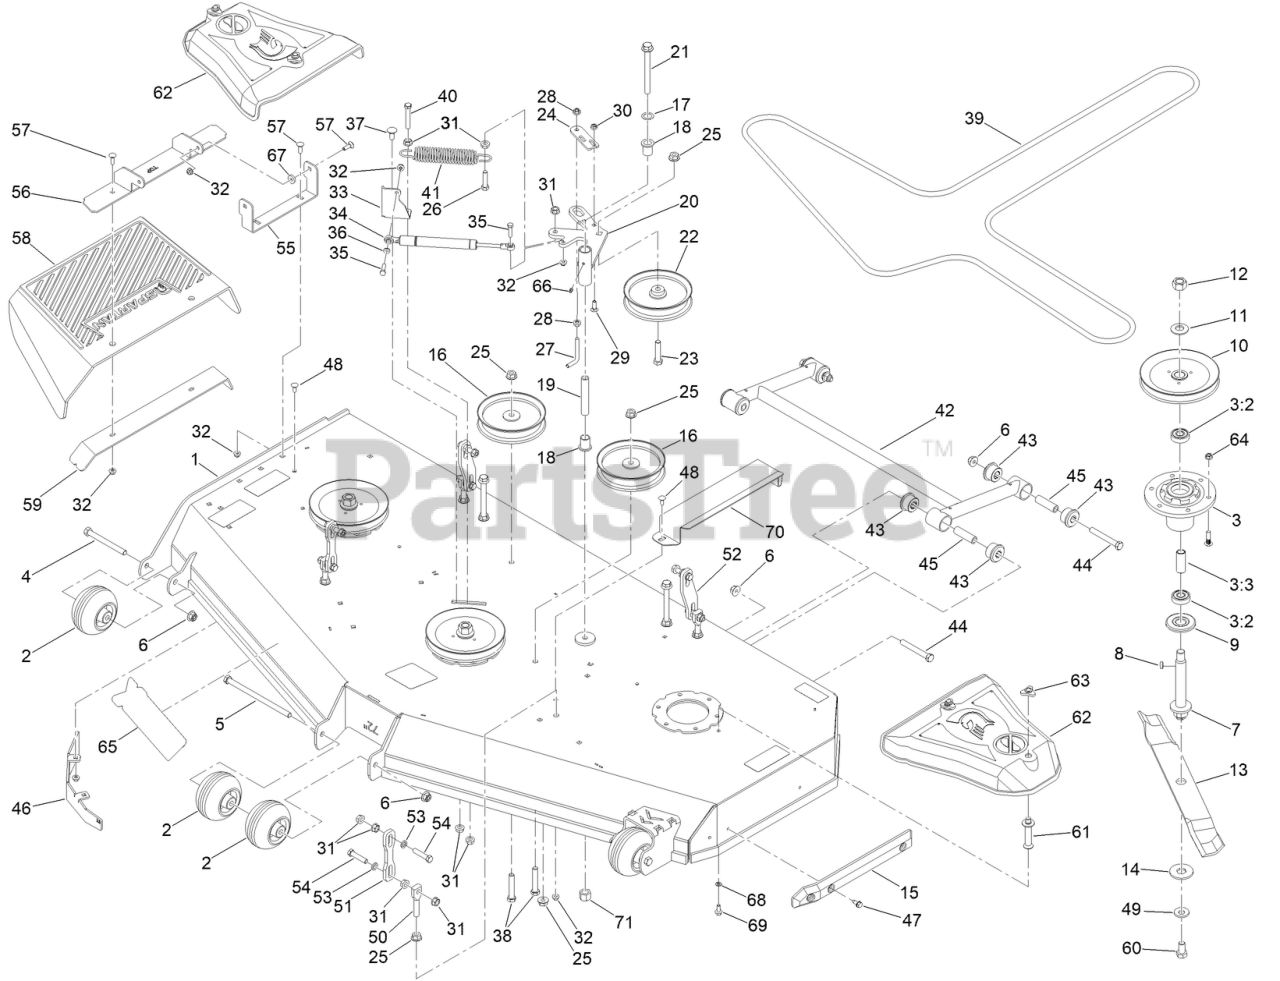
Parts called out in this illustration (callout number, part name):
1	ASM-DECK W/ DECALS
2	MWR ANTI-SCALP WHL W/O GREASE FITTING
3	SPINDLE ASM 6" DECK
3:2	BEARING-BALL
3:3	SPACER, BEARING
4	SCREW-HH
5	1/2-13 X 8-1/2 HEX C/S GR 2 ZINC YELLOW
6	NUT-LOCK
7	SHAFT - SPINDLE
8	6MM X 6MM X 20MM ROUNDED MACHINE KEY
9	GUARD,BEARING TOP .989
10	PULLEY
11	M20 SPRING WASHER (44.5MMOD/ 3.3MM THK)
12	M20X1.5 C8.8 HEX NUT
13	BLADE-ROTARY
14	WASHER-HEX
15	MWR NYLON DECK GUARD
16	6-3/4IN IDLER PULLEY 15/16IN SPACER ASSY
17	.767IDX1.125ODX.016 THK TRIP WV WASHER
18	3/4IN ID X15/16IN OD X 1-1/8IN FLNG BUSH
19	MWR INNER IDLER SPACER
20	MWR DECK IDLER PULLEY ARM ASSY BLACK
21	1/2-13 X 5-1/2 HEX FLANGE BOLT GR 8 ZY
22	6-3/4IN IDLER PULLEY 7/16IN SPACER ASM
23	SCREW-HH
24	DECK IDLER PULLEY BELT RETAINER BRKT
25	NUT-HHF
26	SCREW-HH
27	BOLT-L
28	3/8-16 HEX FLANGE NUT W/SERR ZINC YELLOW
29	BOLT-CARR
31	NUT-HF
32	NUT-HF, NI
33	DECK BELT IDLER DAMPER MTG BRKT BLACK
34	IDLER GAS SPRING
35	SCREW-HH
36	.312IDX.625ODX.062 THK THRUST BRG OI BRZ
37	SCREW-CARR
38	1/2-13 X 2-3/4 HEX FLANGE BOLT (GR.8) YZ
39	72 DECK BELT
41	MWR DECK SPRING
42	72IN DECK FRAME STABILIZER ASSY BLACK
43	RED A80 SUSP BUSHING
44	1/2-13 X 3-3/4 HEX C/S (GR.5) ZC/YEL
45	UTV A-ARM BUSHING SLEEVE
46	BAFFLE-WIPER 72 PAINTED BLACK
47	SCREW-HWH, THREAD CUT
48	BOLT-CARR
49	M16 SPRING WASHER (39MMOD/ 3.9MM THK)
50	MWR DECK HEIGHT ADJUSTMENT STUD
51	MWR DECK SUSP LINK BLACK
52	MWR 72 DECK RR HEIGHT ARM CONN LINK
53	.443 ID X .749 OD X .125 THK NYLON BLACK
54	SCREW-HH
55	MWR CHUTE MTG BRKT BLACK
56	RT/SRT DECK CHUTE HINGE ASSY BLACK
57	5/16-18 X 1 CARRIAGE BOLT GR 8 YZ
58	2020 RT/SRT RUBBER DISCHARGE CHUTE
59	DECK CHUTE HINGE BACKER BRKT BLACK
60	M16X1.5-30MM C10.9 HEX BOLT
61	PIN-BELT COVER
62	COVER-BELT
63	NUT-KNOB
65	DECAL-DECK, 72-XFT
66	1/4IN DRIVE TYPE GREASE FITTING YZ
67	.312 ID X .875OD X .1875 THK F/W NYL
68	WASHER-LOCK
69	SCREW-HHF
70	BRACKET-COVER 72
71	NUT-LOCK, NI
